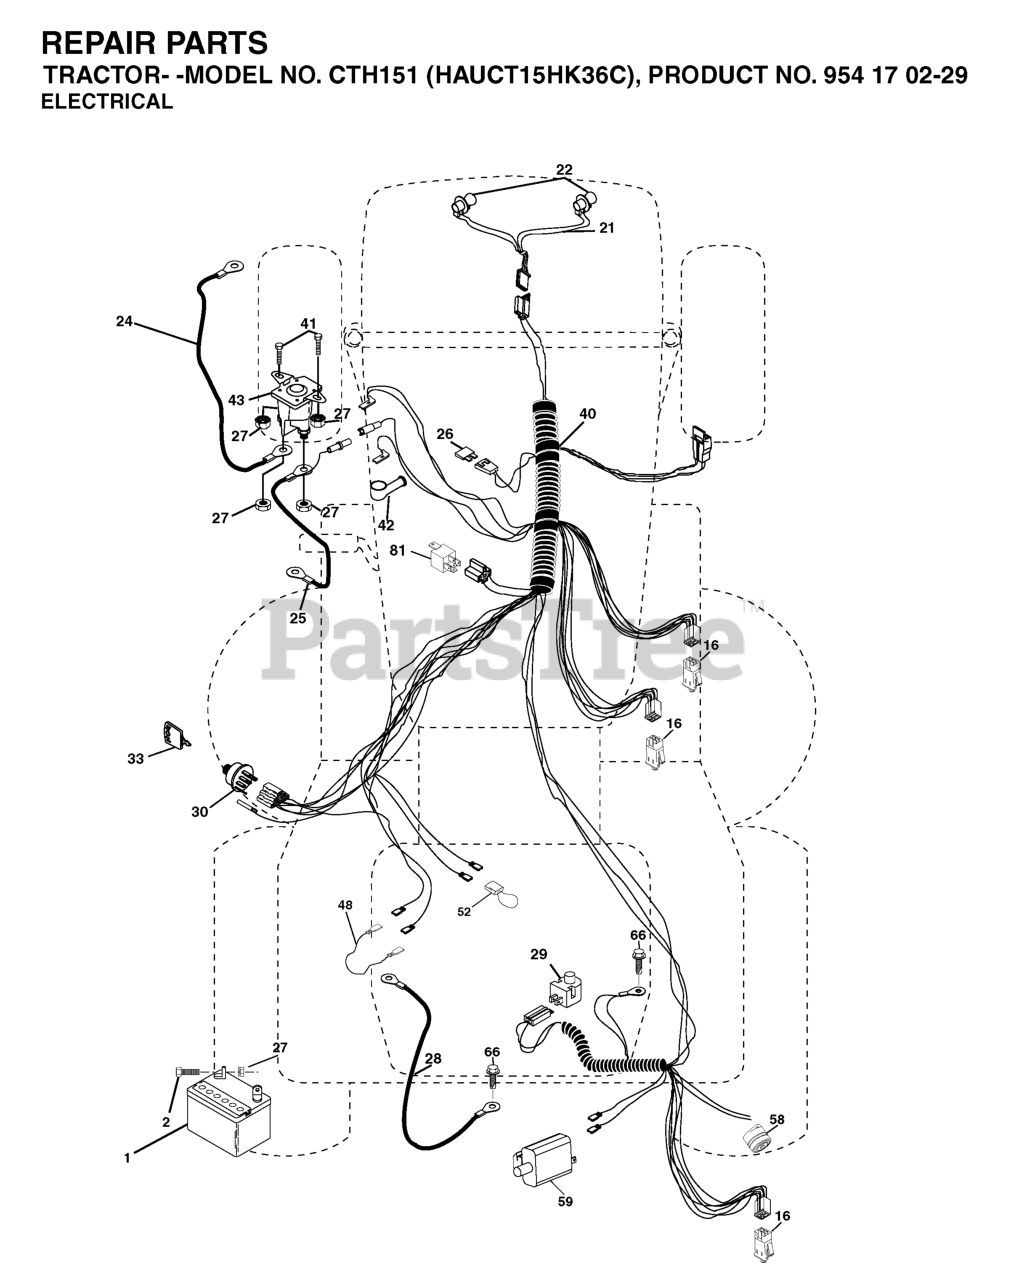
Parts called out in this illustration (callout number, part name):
1	BATTERY 12V .35 AMP
2	BOLT.HEX.1/4.X.3/4.DICHROMATE
16	SWITCH INTERLOOK PUSH-IN
21	HARNESS.W/LIGHT SOCKET
24	BATTERY CABLE GT
25	CABLE BATTERY
26	FUSE 20AMP
27	NUT
28	CABLE GROUND
29	RP.SWITCH.PLUNGER.NC.GRAY
30	IGNITION SWITCH
33	KEY MLD GEN DELTA
41	BOLT
42	TERMINAL COVER
43	SOLENOID
48	ADAPTER.AMMETER
52	WIRE PROTECTION LOOP
58	BUZZER
59	.WITCH.FULL BAGGER.INDICATOR
81	RELAY.ASSY.T
